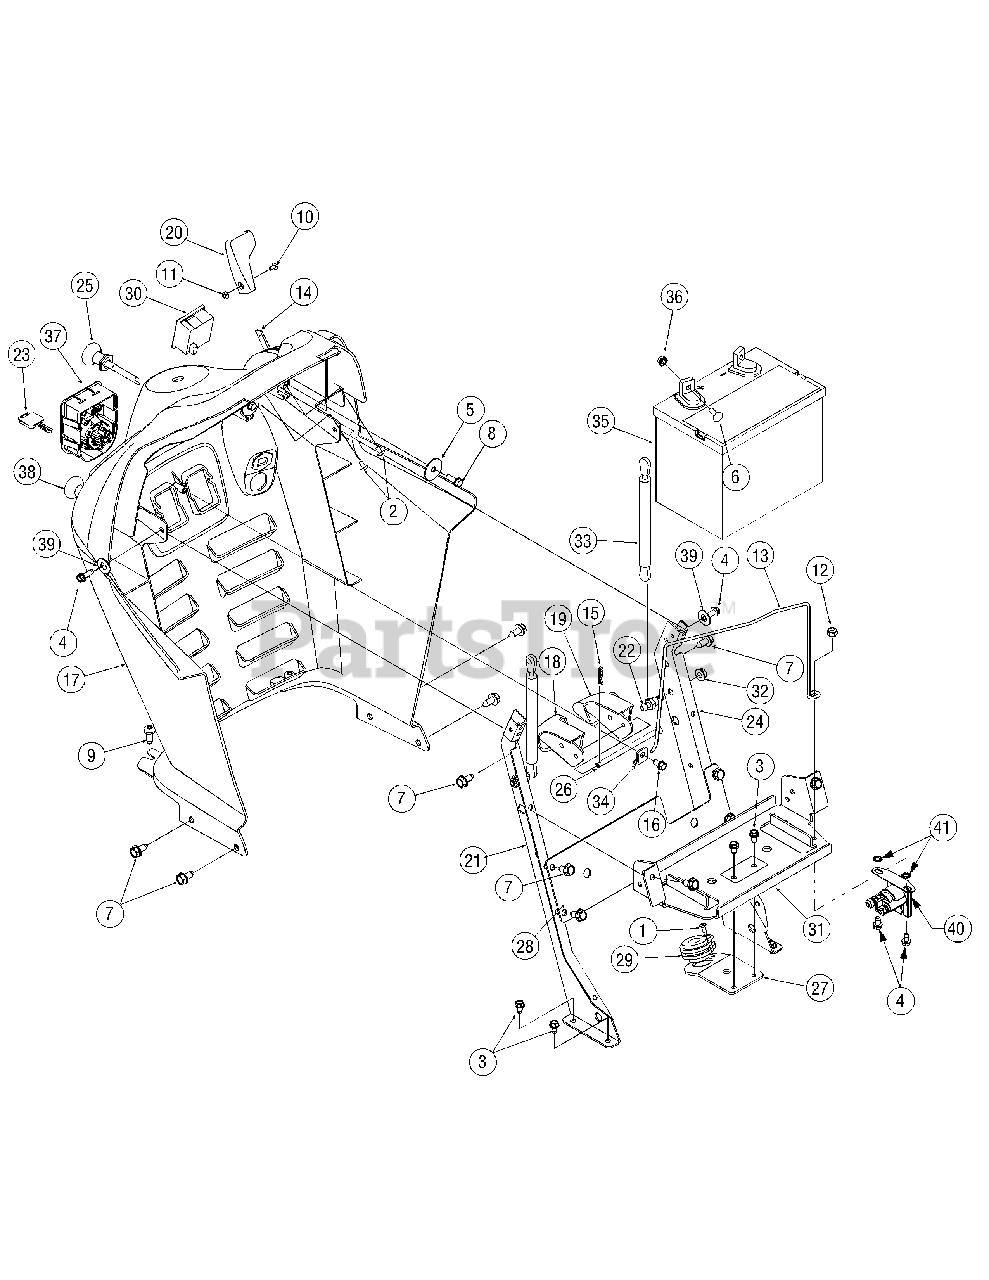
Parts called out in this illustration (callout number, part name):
1	Screw, #10-18 x.50
2	Screw, #10-24 x.375
3	Screw, Self-tapping, 1/4-20, 0.500
4	Screw, Hex. 1/4-20 x.75
5	Flat Washer,.330 x 1.25 x.06
6	Screw, Carriage, 1/4-20,.75,
7	Screw, Hex, 5/16-12 x.75
8	Screw, 1/4-15, 0.750
9	Screw, Torx Hd. Tapp. 5/16-18 x.75
10	Screw, Machine, #8-32, 0.375, Trus Phillips
11	Nut, 8-32
12	Nut, Nylon Lock, 1/4-20
14	Control, Throttle, 38.0
15	Internal Cotter Pin,.072 x 1.13
16	Screw, 1/4-15 x.50
17	Dash
18	Lever, Dash, Cruise
19	Lever, Dash, Brake
20	Knob, Throttle Control
23	Ignition Key, Plastic
26	Rod,.250 Dia x 4.25
30	Monitor, Systems Indicator / Hour Meter
33	Gas Spring Cylinder, 3.62 Stroke
35	Battery, 235 CCA
36	Nut, Sems, 1/4-20
37	Switch Module, Ignition
38	Switch, PTO, Yellow
39	Flat Washer,.28 x.74 x.063
40	Solenoid, 12V, 100 Amp
41	Washer, External Lock, 1/4
